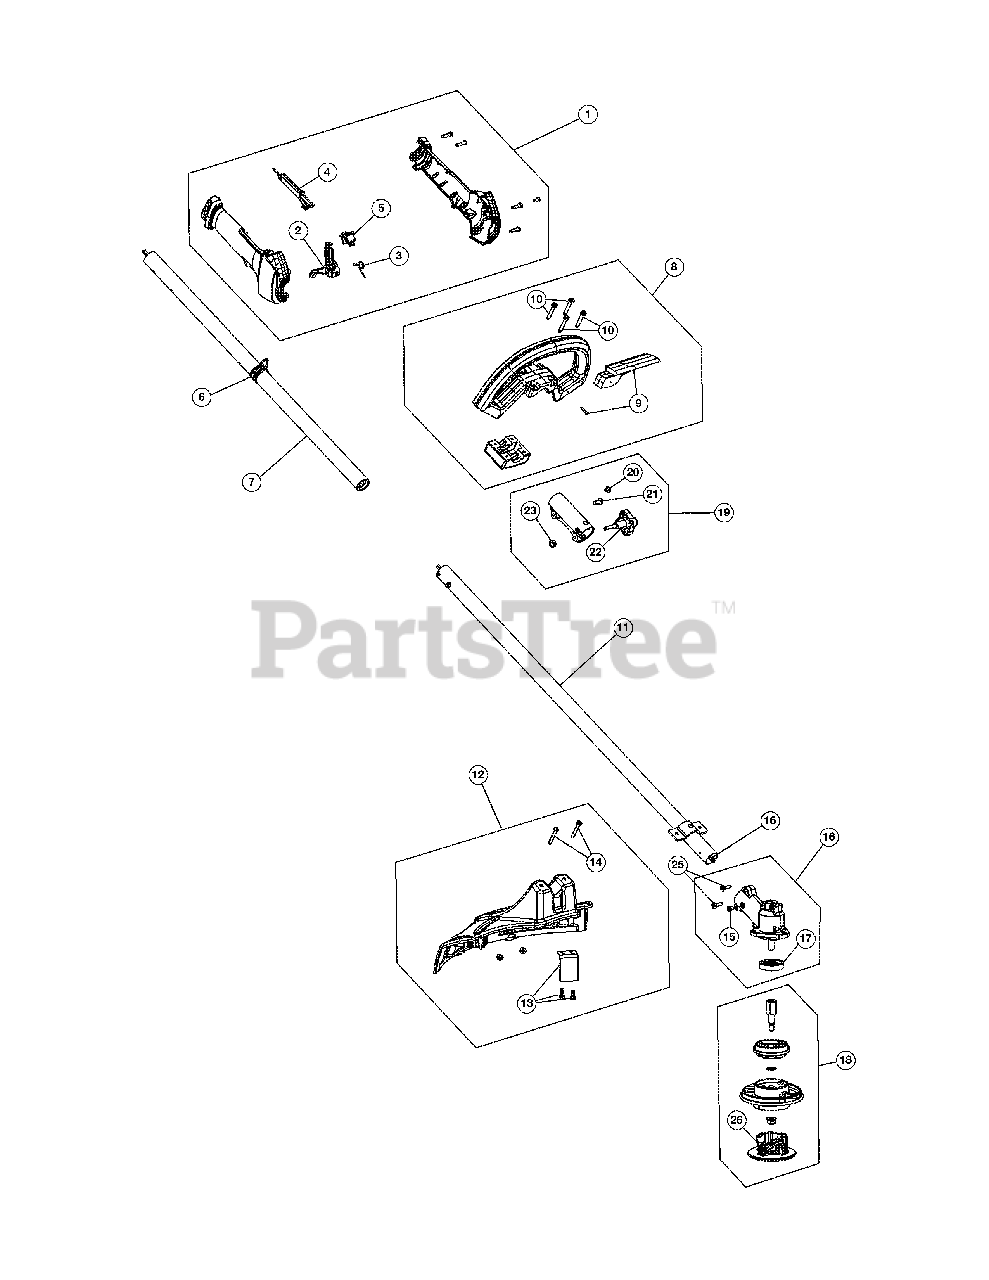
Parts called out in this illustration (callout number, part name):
1	Throttle Housing Assembly (Incl. Ref No. 2-5)
2	Throttle Trigger
3	Spring
4	Throttle Lock-out
6	Shoulder Strap Clip
7	Upper Drive Shaft Housing Assembly
8	Handle Assembly (Incl. Ref No. 9 & 10)
9	Barrier Bar Assembly
11	Lower Drive Shaft Housing Assembly
12	Shield Assembly (Incl. Ref No. 13 & 14)
13	Blade Assembly
15	Anti-Rotation Screw
16	Gear Box (Incl. Ref No. 15, 17 & 25)
17	Gear Box Spacer
18	Cutting Head Assembly (Incl. Ref No. 26)
19	Split Boom Coupler (Incl. Ref No. 20-23)
22	Adjustment Knob
23	Knob Retaining Nut
24	Lower Flexible Drive Shaft
25	Gear Box Screw
26	Cutting Head Cap
